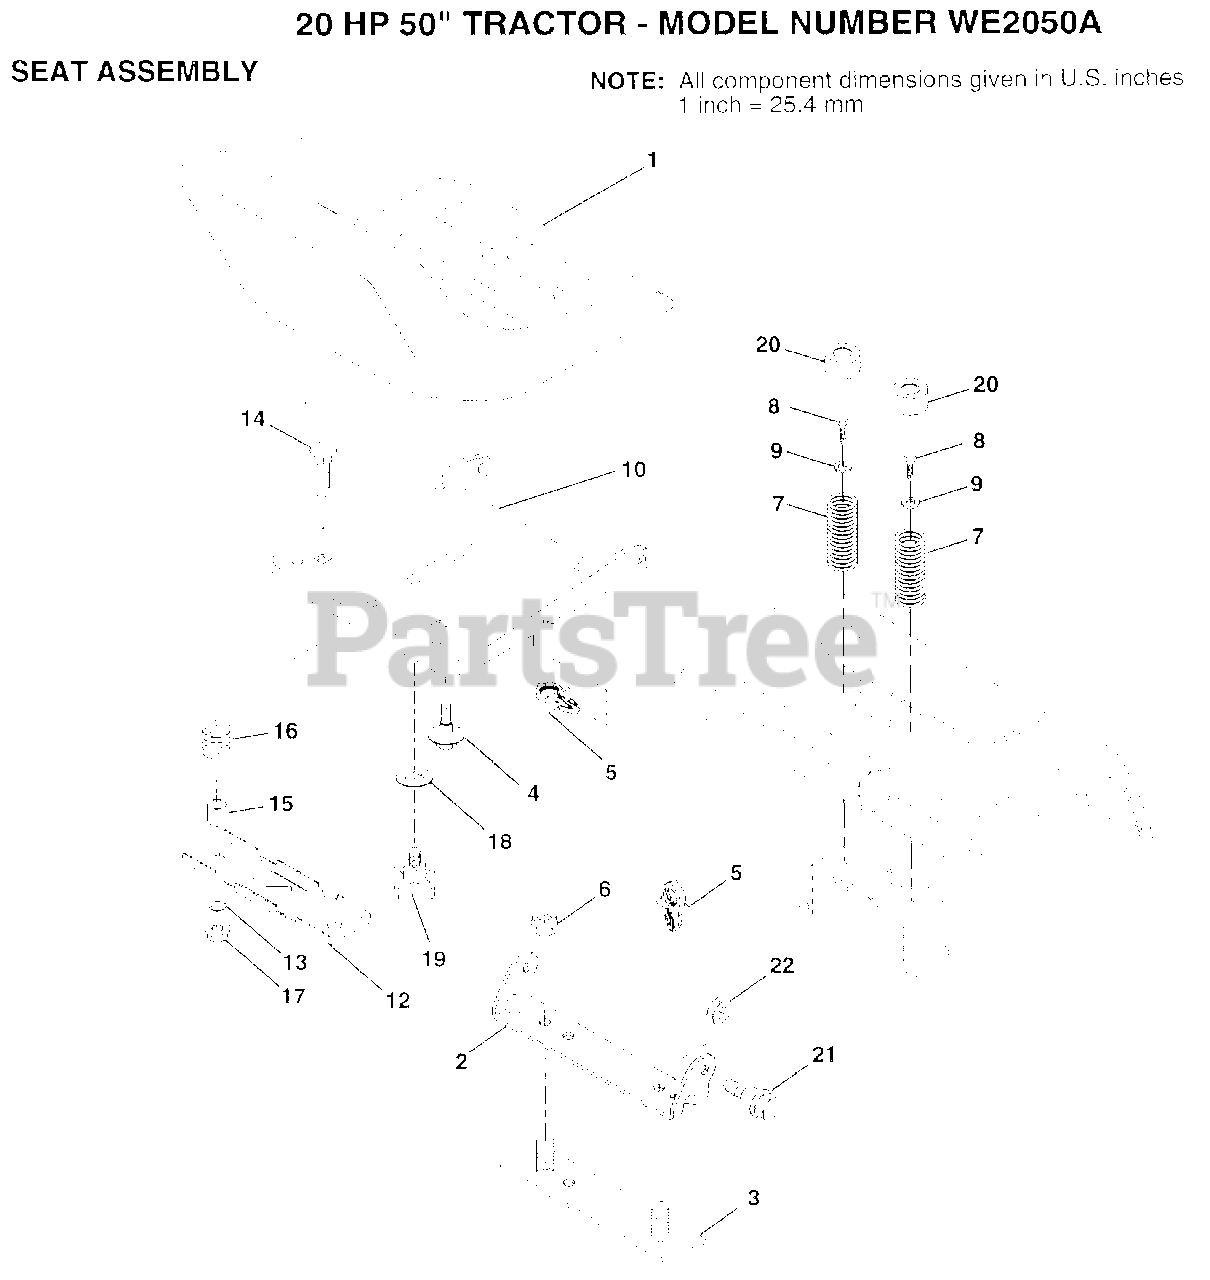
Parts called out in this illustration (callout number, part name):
2	BRACKET PVT SEAT
3	STRAP ASM FENDER
4	"BOLT,SHOULDER"
5	CLIP PUSH - IN
7	SPRING COMPRESSIO
8	SCREW LT
9	WASHER
12	BRKT SWITCH
13	BUSHING
15	SPACER SPLIT
16	SPRING COMPRESSED
18	WASHER
19	"KNOB 1/2"" YT"
20	CAP SPRING
21	BOLT.SHLD.5/16-18
